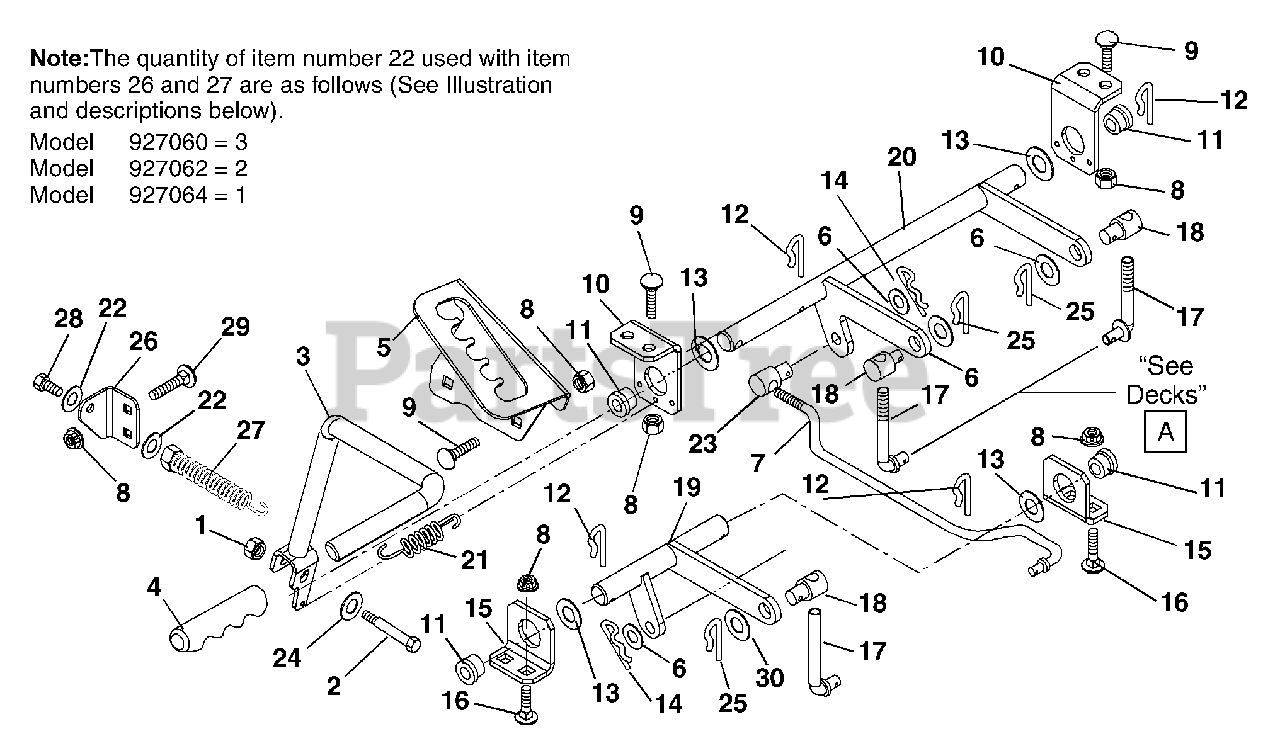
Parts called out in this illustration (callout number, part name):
1	Nut, Locking Top Flange .31-18
2	Bolt, 1.25 Socket Shoulder Plain
3	Weldment, Lift Handle
5	Detent Plate
6	Washer, Flat Steel .511 x 1.44 x .125
7	Rod, Deck Lift
8	Nut, Locking Top Flange .38-16
9	Bolt, Round Head Square Neck .38-16 x .75 Grade 5
10	Bracket, Lift
11	Bushing, Flange .75 x 1.00 x .625 x 1.25
12	Pin, Spring Clip
13	Washer, Flat Steel .563 x 1.38 x .109
14	Pin, Hair #16
15	Bracket, Deck Pivot
16	Bolt, Round Head Square Neck .38-16 x 1.00 Grade 5
17	Rod, Link (060, 062)
17	Rod, Link (064)
18	Trunnion (030)
18	Trunnion (064)
19	Weldment, Front Lift (060, 062)
19	Weldment, Front Lift (064)
20	Weldment, Lift
21	Spring, Extension
22	Washer, Flat Steel .43 x 1.00 x .16 (060)
22	Washer, Flat Steel .43 x 1.00 x .16 (062)
22	Washer, Flat Steel .43 x 1.00 x .16 (064)
23	Pivot, Rod
24	Washer, Flat Steel .43 x 1.00 x .160
25	Clip, Spring
26	Bracket, Spring Anchor
27	Spring, Tension .195 x 1.15 x 5.50
28	Bolt-Hex .38-16 x 1.50 Grade 5
29	Bolt, Round Head Square Neck .38-16 x .75 Grade 5
30	Washer, Flat Steel .563 x 1.38 x .109
